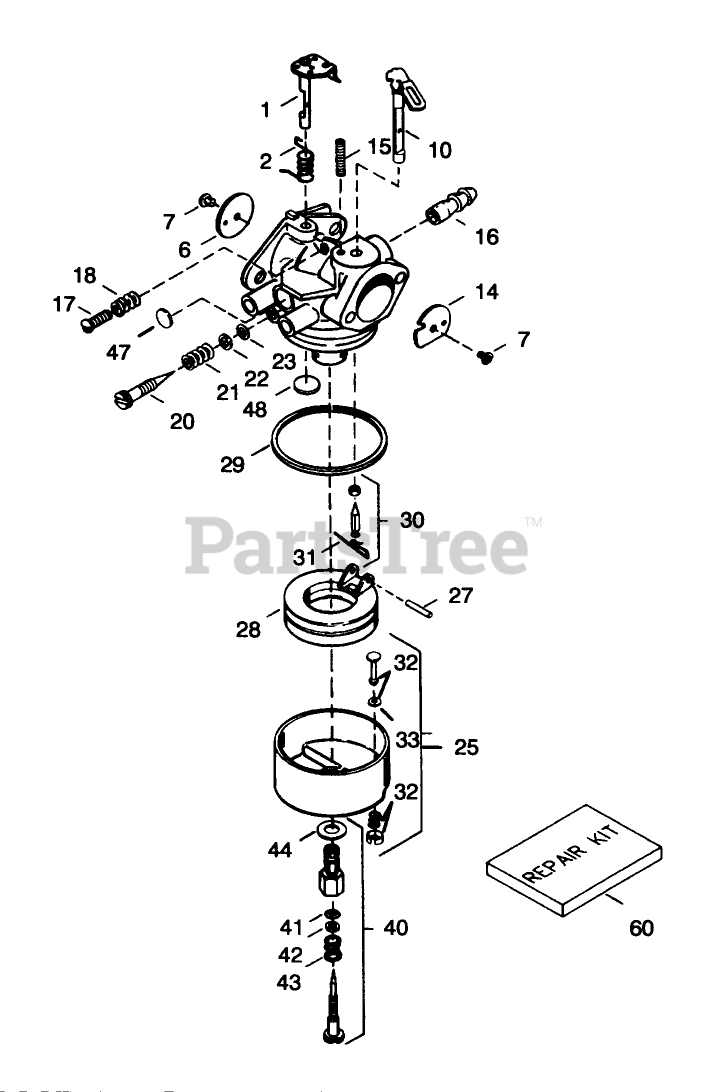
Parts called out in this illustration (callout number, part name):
1	Throttle Shaft and Lever ASM
2	Spring-Return, Throttle
6	Shutter-Throttle
7	Screw-Shutter
10	Choke Shaft and Lever ASM
14	Shutter-Choke
15	Spring-Positioning, Choke
16	Fitting-Fuel
17	Screw-Throttle Crack Screw / Idle Speed
21	Spring-Tension
22	Washer
23	ORing
24	Screw-Idle Mix
25	Float Bowl Asm. (Incl. Ref. # 32, 33)
27	Shaft-Float
28	Float
29	O Ring-Bowl, Float
30	Inlet Needle, Seat Clip Assy. (Incl. No. 13)
31	Clip-Spring
32	Bowl Drain ASM
33	Gasket-Plunger, Drain
40	Adjustment Screw Assy.,Main (Incl. Ref. #5A,21,23 30)
41	ORing
42	Washer
43	Spring
44	Washer-Bowl Nut
47	Plug-Welch, Idle Mixture Well
48	Plug-Welch, Atmospheric Vent
60	Kit-Repair
